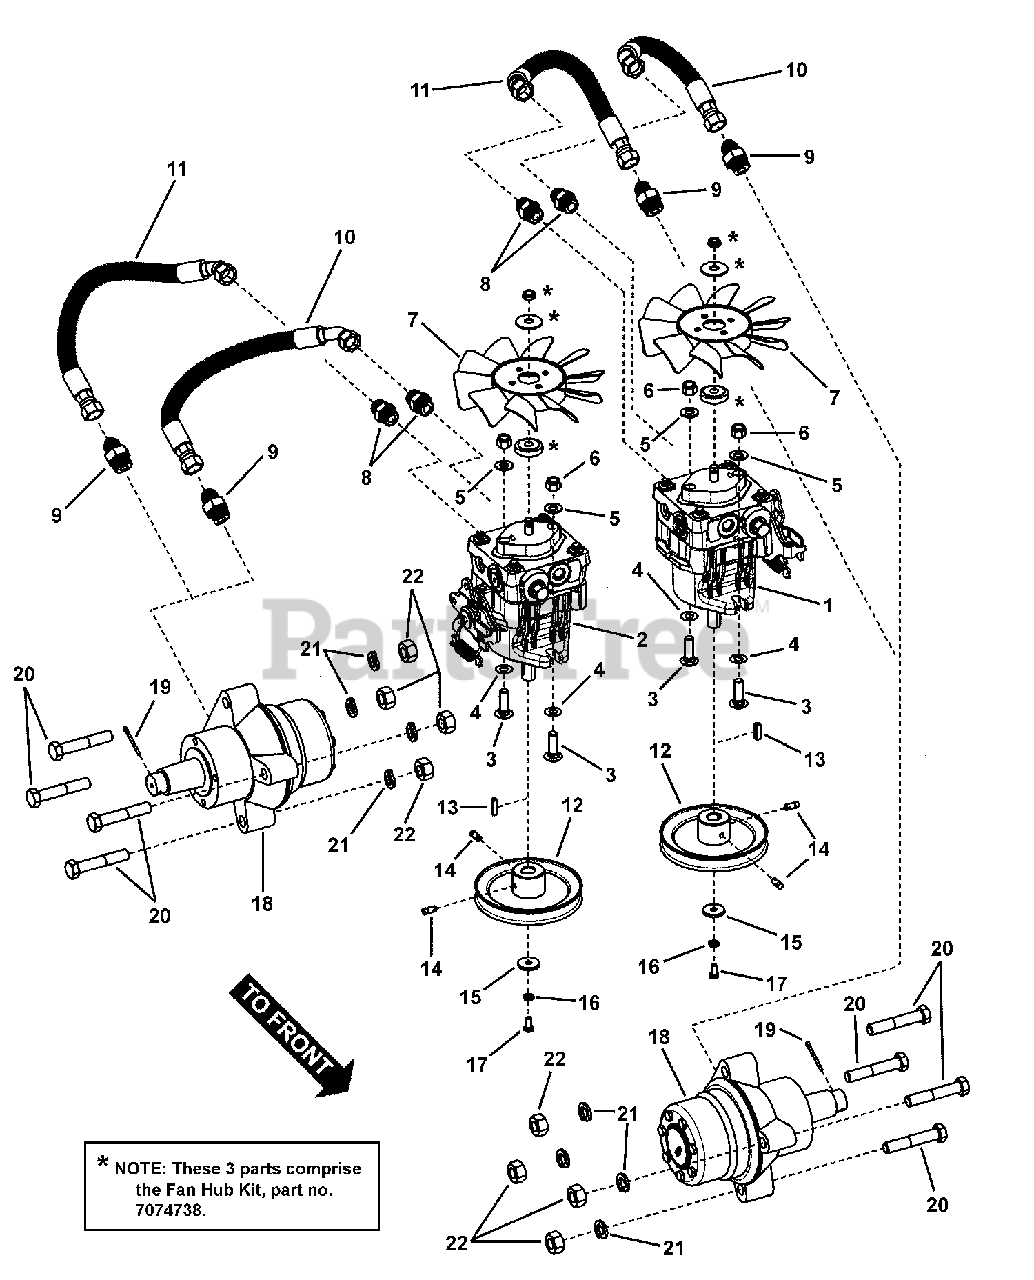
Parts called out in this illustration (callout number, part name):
1	PUMP, Hydro-Gear (Left Hand)
2	PUMP, Hydro-Gear (Right Hand)
3	BOLT, 3/8-16 x 1-1/4" Short Neck Carriage, GR 5
4	RETAINER, 3/8" Bolt
5	WASHER, 3/8" SAE Flat
6	NUT, 3/8-16 HEX NYLON LOCK
7	FAN, 7" Nylon, Counter-Clockwise
8	FITTING, Hydraulic
9	FITTING, Hydraulic
10	HOSE, 19" Hydraulic
11	HOSE, 22" Hydraulic
12	Pulley, Pump, Hydro Drive (5.00" O.D.)
13	KEY, M5 x M20
14	SET SCREW, 1/4-20 x 1/2" Socket Head w/ Patch Lock
15	WASHER, 1/4 x 1x 1/8" Flat
16	WASHER, 1/4" Split Lock
17	SCREW, M6 1.0X12MM, Hex Head, CZ
18	WHEEL MOTOR, Hydro Gear (HGM-12C-4005)
19	COTTER PIN, 1/8 x 1-1/4"
20	BOLT, 1/2-13 X 2-3/4 GD5 CZ
21	WASHER, 1/2" Split Lock
22	NUT, 1/2-13 HEX
